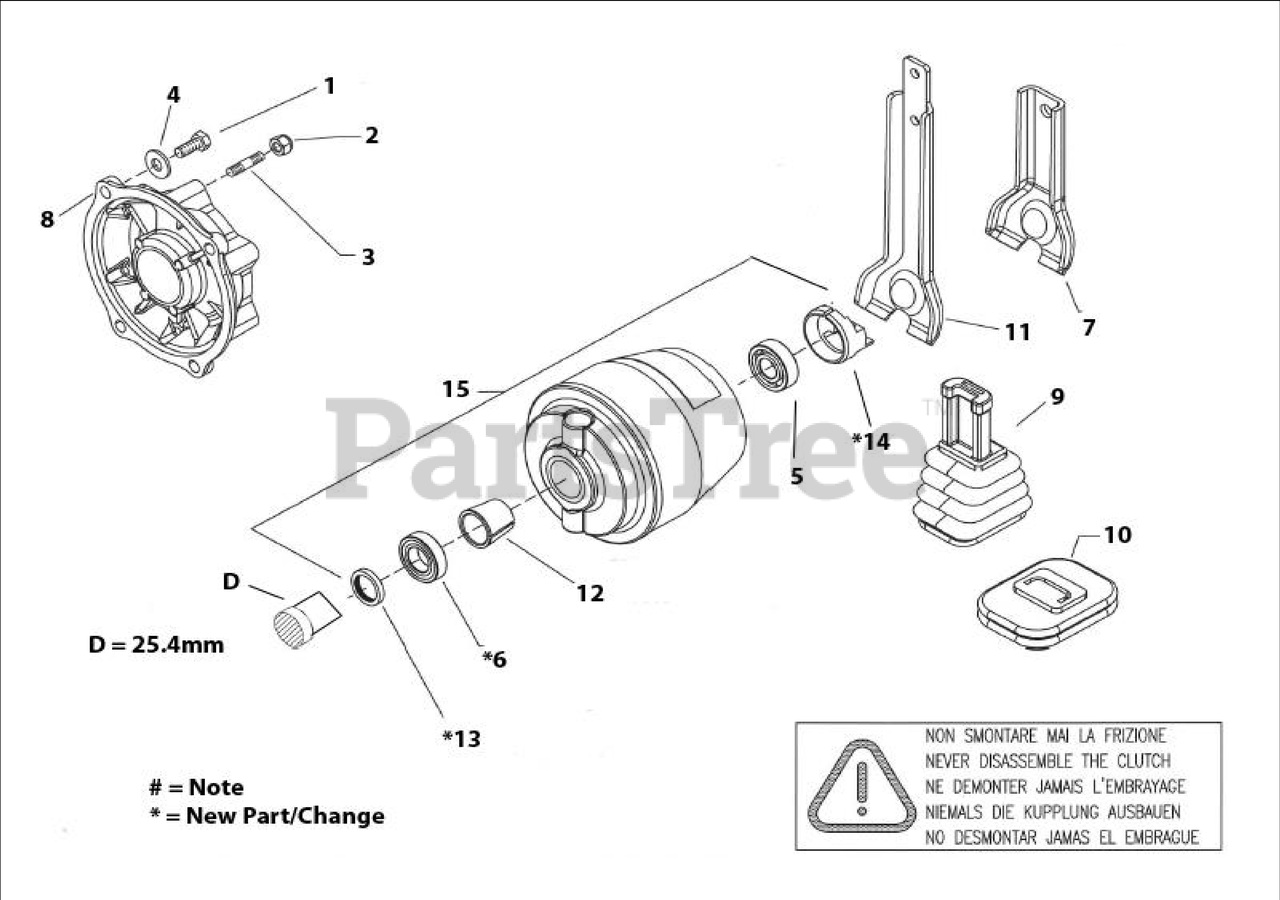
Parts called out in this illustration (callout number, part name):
1	SCREW HH 3/8” X 1
2	LOCKNUT M8 SELF LOCKING
3	STUD M8X40X14X14
4	WASHER LOCK M10.4
5	BEARING 17x40x12 6203 2RS/C3 SKF
6	BEARING 30X55X13 6006 2RS/C3 SKF
7	CLUTCH FORK (ELECTRIC START)
8	FLANGE, ENGINE
9	BOOT/BELLOWS (RECOIL START)
10	BOOT/BELLOWS (ELECTRIC START)
11	CLUTCH FORK (RECOIL START)
12	TAPERED BUSHING D=25.4mm
13	SPACER 5 MM D=25.4mm
14	PUSHER CONE
15	CLUTCH (Includes # 5,*6,12,*13 & *14 )
